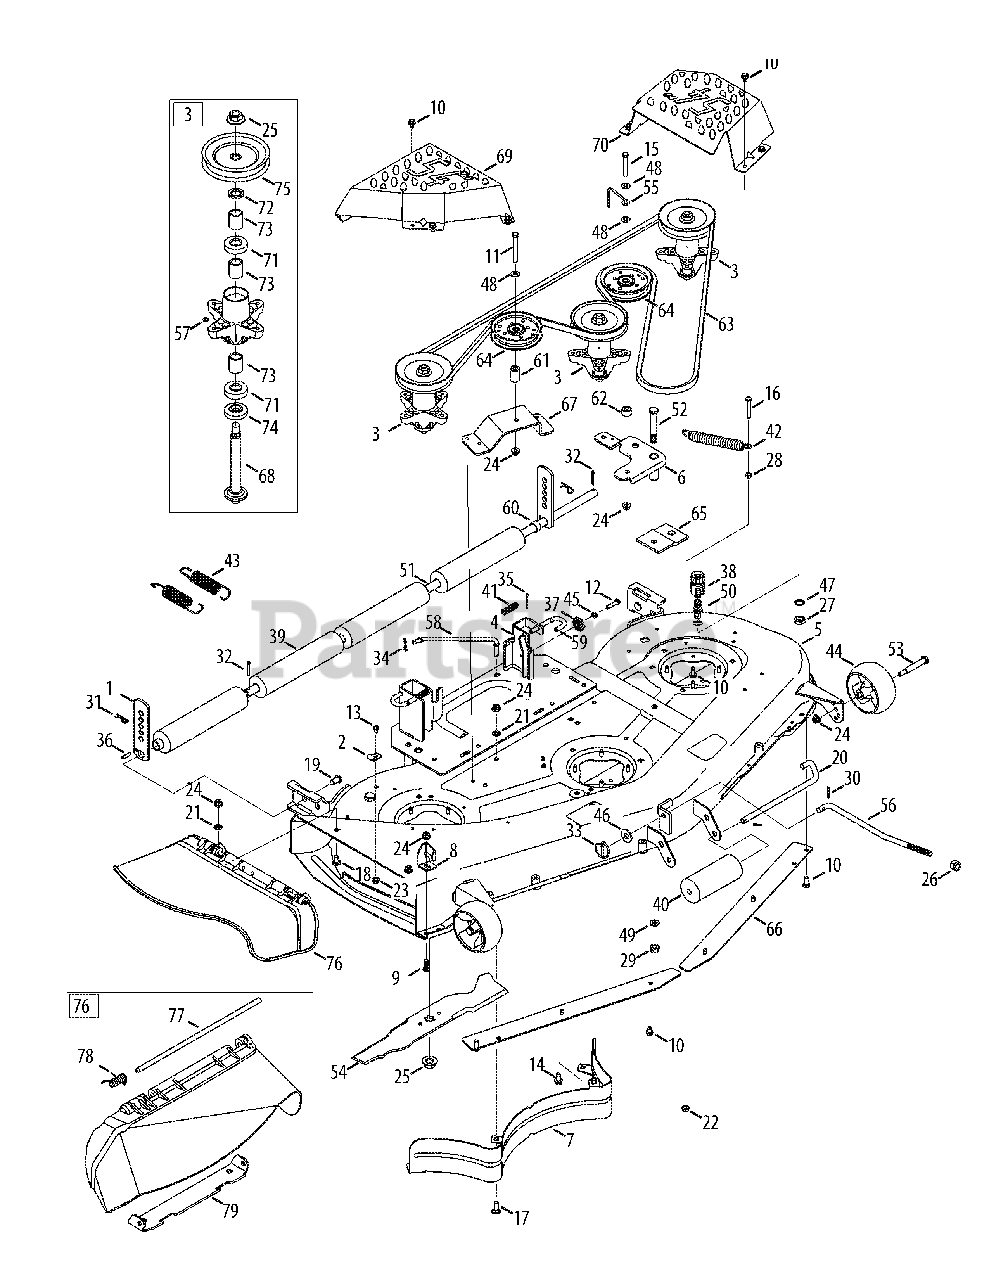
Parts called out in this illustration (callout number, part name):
1	Bracket, Height Adjustment
2	Retainer Hook Brkt.
3	Spindle Assembly
4	Deck Adjustment Bracket w/Weld Nut
7	RR Inner Baffle
8	Chute Stop Deflector
9	Screw, 3/8-16 x 1.0
10	S-Tapp Scr 5/16-18 x .75
11	Screw, 3/8-16 x 3.0
12	Hex Bolt 5/16-18 x 1.25
13	Hex Scr 1/4-20 x 1.00
14	Screw, 3/8-16 x 0.75
15	Screw, 3/8-16 x 2.5
16	Hex Hd Cap Scr. 5/16-18 x 2.0 Gr. 5
17	Carriage Bolt 3/8-16 x 1.0
18	Short Neck Carriage Bolt 3/8-16 x .75
19	Clevis Pin .50 Dia. x .78
20	Roller Pin .5" Dia x 7.31
21	Push Nut 3/8
22	Flange Locknut 5/16-18 Gr. F, Nylon
23	Flange Lock-Nut 1/4-20 Gr. F Nylon
24	Flange Lock-Nut 3/8-16 Gr. F Nylon
25	Hex Flange Nut 5/8-18
26	Flexlock Nut, 1/2-13
27	Hex Nut, M16-1.5
28	Hex Nut 5/16-18 hd. (Gr. 5)
29	Hex L-Nut 1/2-13
30	Cotter Pin 3/32 x 1.0
31	Cotter Pin
33	Linch Pin .1875
34	Bow Tie Cotter Pin
35	Cotter Pin 1/8" Dia x 1.25
36	Spring Pin 1/4 Dia. x 1.0
37	Deck Ad just ment Gear
38	Water Noz zle Adap tor
40	Front Roller
41	Compression Spring .535 OD x 1.751 Lg.
42	Extension Spring .85 Dia. x 5.915
43	Extension Spring 1.5 x 5.99
44	Deck Wheel 5.0
45	L-Wash 5/16 ID
46	Flat Washer .531 x 1.25 x .100
47	Lockwasher 5/8
48	Flat Washer .406 x .875 x .059
49	Lockwasher
51	Shaft .75 x 47.12
52	Shoulder Screw
53	Shoulder Screw
55	Idler Belt Keeper Rod
56	Deck Lift Rod
58	Deck Sway Rod
59	Deck Release Pin
60	Spacer .82 ID x 1.0 OD x .53
61	Spacer .380 ID x .90 OD x 1.313
62	Spacer .385 ID x .88 OD x .64
64	Idler Pulley w/Flange 4.25 Dia
65	Bracket, Stabilizing
68	Spindle Shaft, 6.95" Lg.
69	Spindle Cover RH
70	Spindle Cover LH
71	Ball Bear ing .787 ID x 1.85 OD x .551
72	Spacer .790 ID x 1.25 OD x .175
73	Spacer .79 x 1.82 x .55
74	Spacer .79 ID x 1.82 OD x .55
76	Chute Assembly
78	Torsion Spring .44 ID x 2.0
79	Chute Bracket
